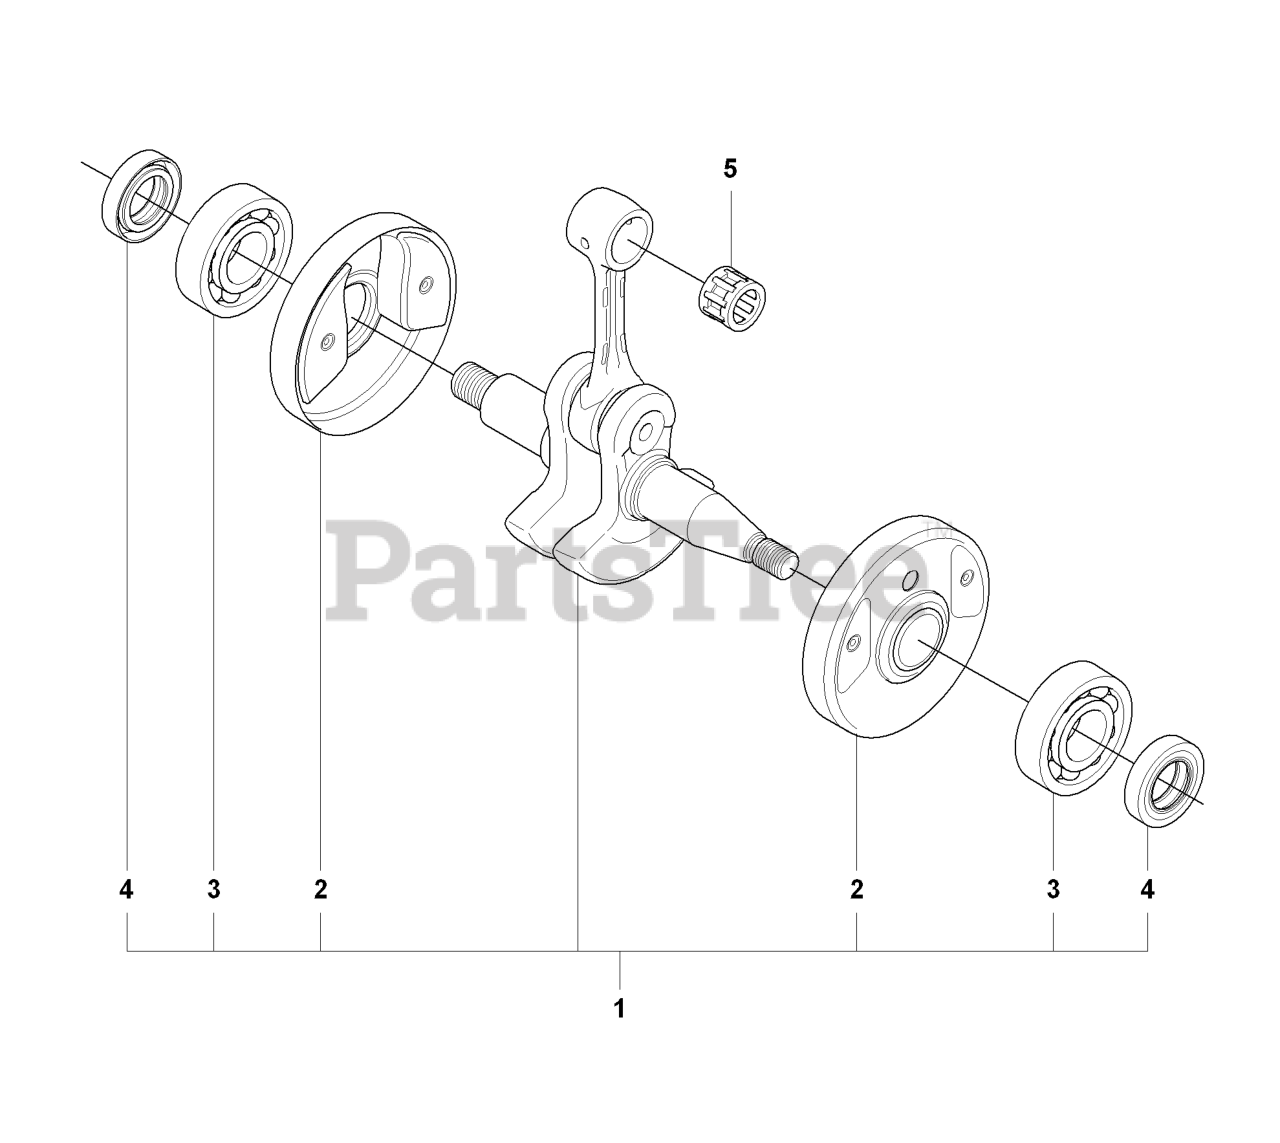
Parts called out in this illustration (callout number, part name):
3	BALL BEARING-6202-C3 SKF
4	SEALING RING
5	SUPPORT BUSHING
